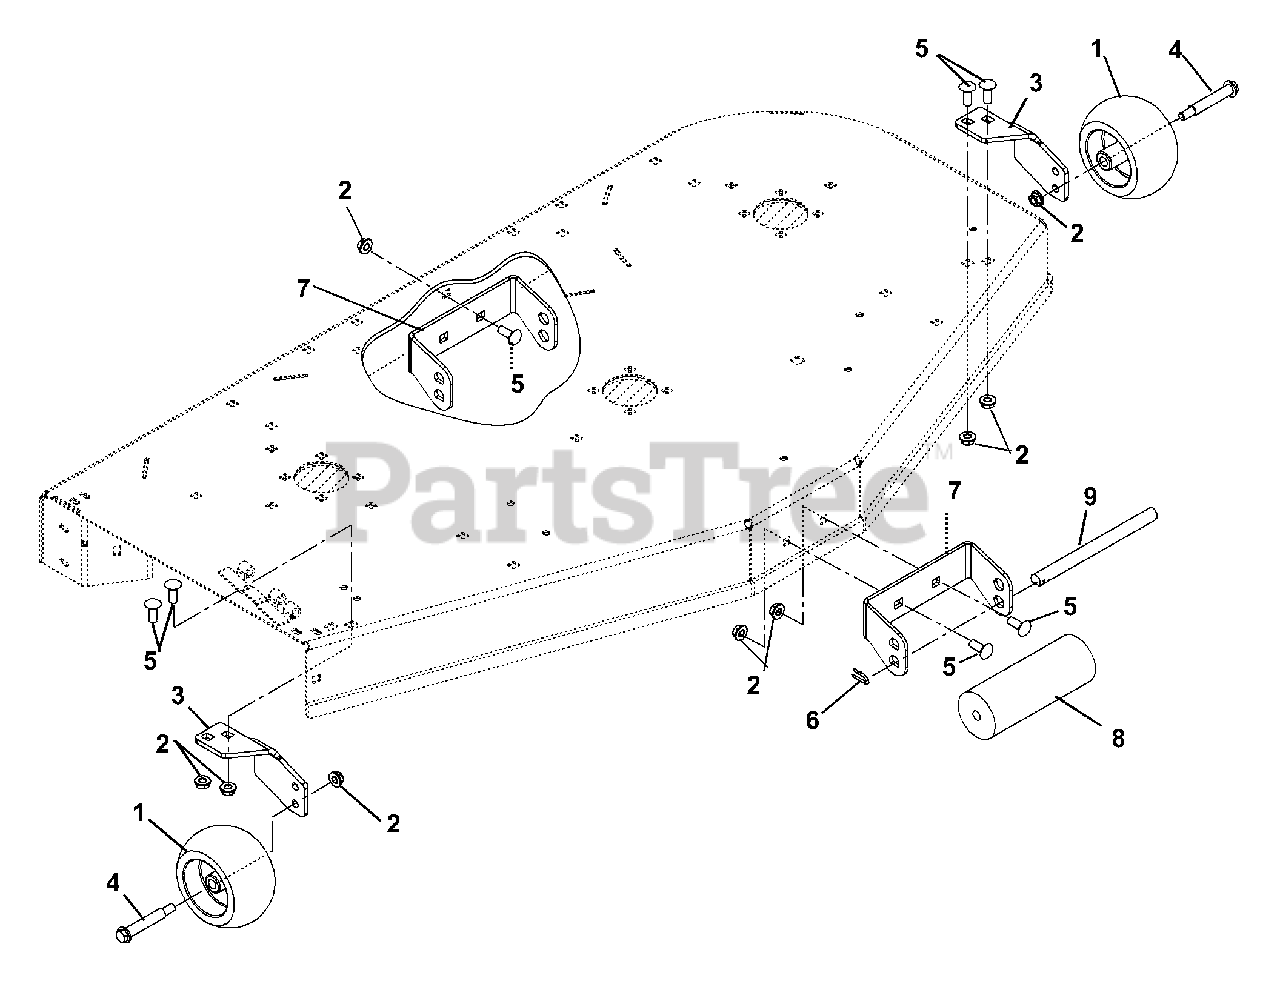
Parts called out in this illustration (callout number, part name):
1	WHEEL 5 X 3
2	@NUT-LK-NYL-FLG .38-16 YWZC
3	BRACKET, ANTI SCALP
4	BLT-SHLDR .38-16X2.50 HWH G5
5	@BLT-RDHDSQNK .38-16X1.00 G5YZ
6	PIN, SPRING CLIP
7	BRACKET, ROLLER MOUNT
9	PIN, ROLLER
